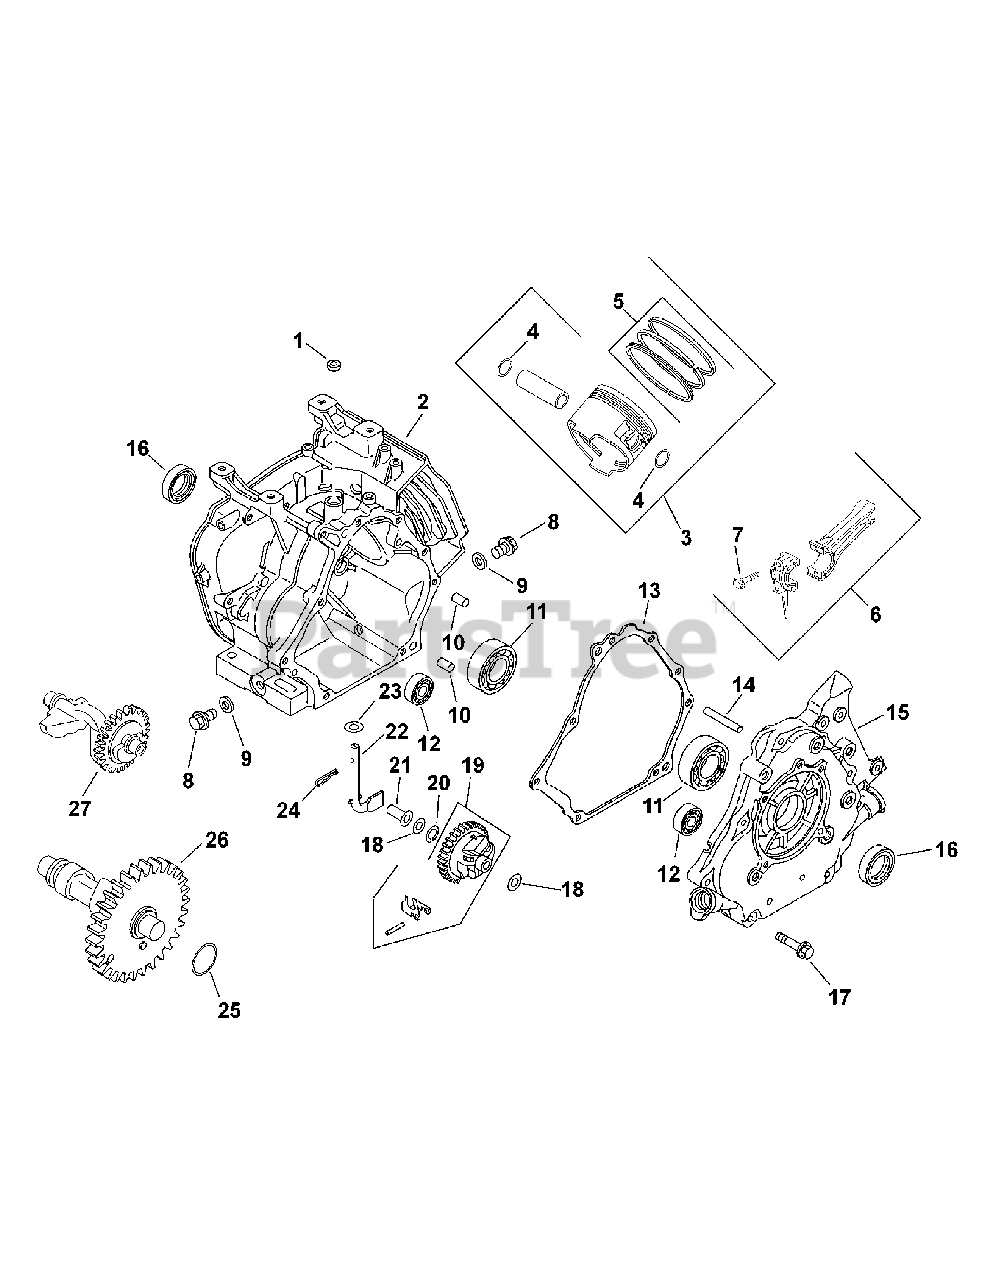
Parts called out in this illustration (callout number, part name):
2	Crankcase
3	Piston w/ Ring Set (.50) (Incl. 4, 5)
3	Piston w/ Ring Set (.25)
3	Kit, Piston w/ Ring Set (Std)
4	Ring, Retainer
5	Ring Set (Std)
5	Ring Set (.25)
5	Ring Set (.50)
6	Connecting Rod (Includes 7)
7	Bolt, Conn Rod
11	Bearing, G.r.
14	Shaft, Governor
15	Closure Plate
16	Oil Seal, G.R.
17	Screw, Flange
19	Governor Gear Assembly
22	Shaft, Governor Cross
27	Balance Shaft
